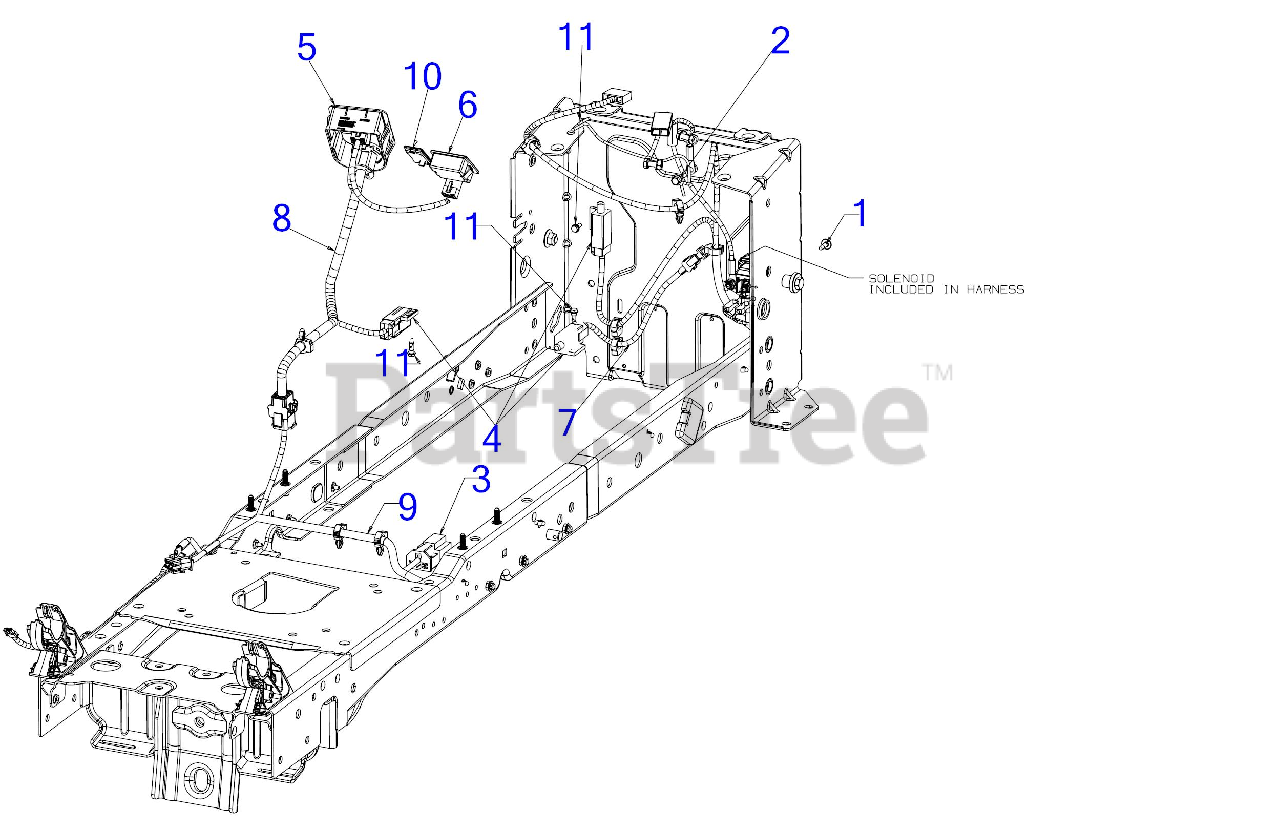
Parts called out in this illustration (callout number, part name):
1	SCREW M6-1 x .625
2	SCREW 1/4-20X.625
3	3 POLE SWITCH ( NC-NO-NO)
4	INTERLOCK SWITCH (NO/NC)
5	KEY SWITCH MODULE
6	HOUR/SVC METER
7	REVERSE HARNESS
8	DASH HARNESS
9	MAIN HARNESS M-PTO/RMC/HRMTR
11	SHOULDER SCREW
